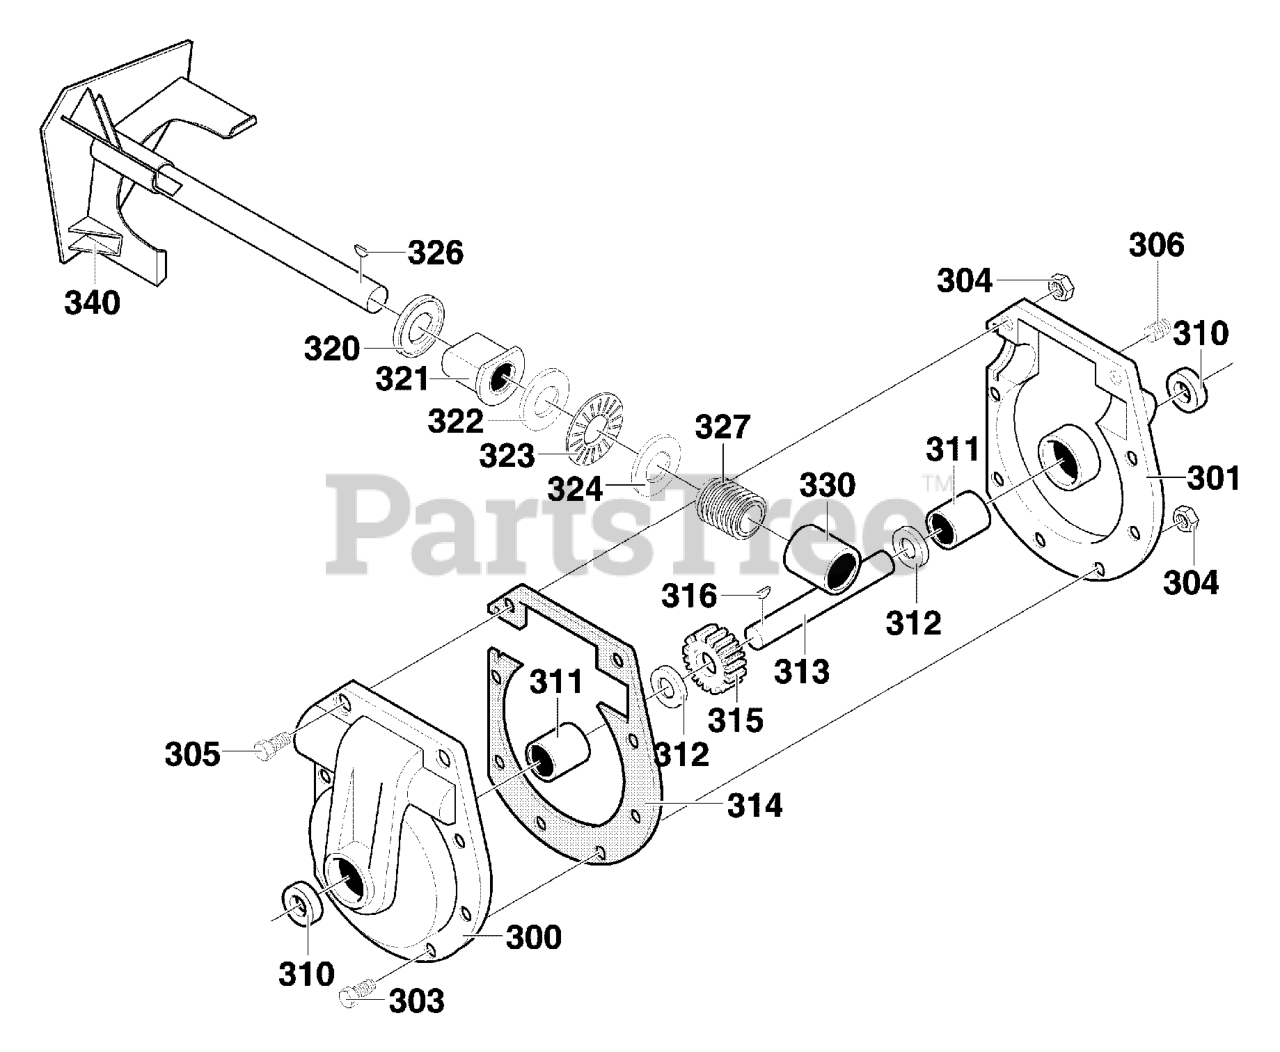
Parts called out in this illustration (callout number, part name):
300	CASE, GEAR, RH
301	CASE, GEAR, LH
303	SCREW,1/4-20X.75
304	NUT,1/4-20
305	NUT, 1/4-20 HEXKEPS
306	SCREW, 3/8-16 x 0.50
310	SEAL, OIL
311	BEARING, FL
312	WASHER, FLAT
313	SHAFT, AUGER OUTPUT
314	GASKET, GEAR BOX
315	WORM GEAR
316	KEY, WOODRUFF #61
320	BRNG, FL
321	SHAFT, AUGER INPUT
322	COLLAR, THRUST
323	PIN, SPRING
324	WASHER, FLAT
326	BRNG, FL
327	SEAL, OIL
330	BEARING
340	IMPELLER
